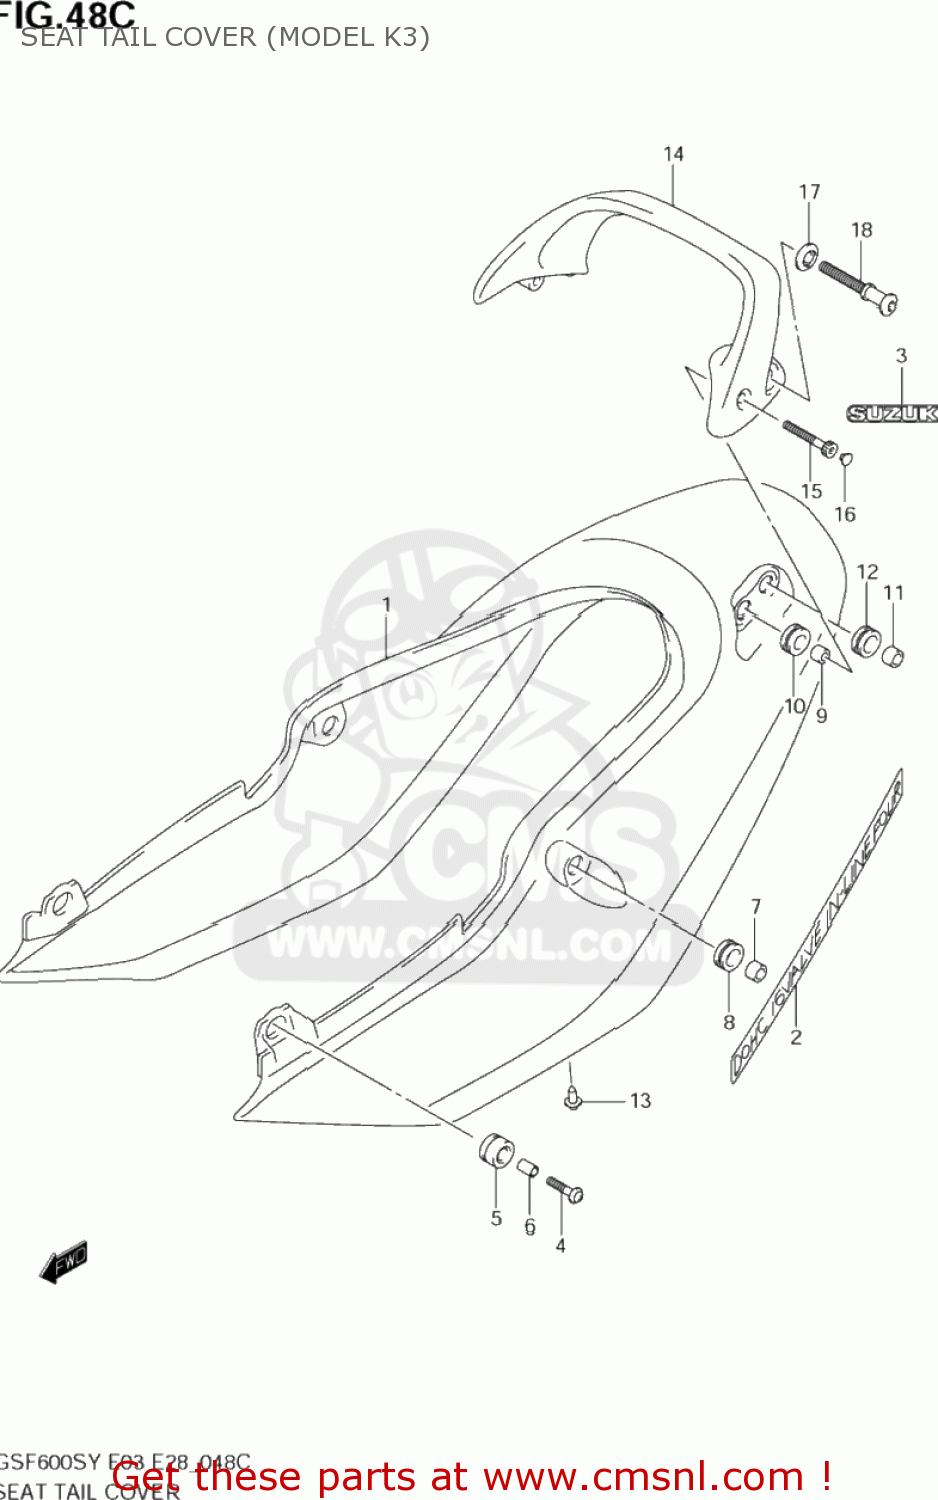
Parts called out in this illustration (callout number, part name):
1	COVER,SEAT TAIL
2	EMBLEM,SEAT TAIL COVER
3	EMBLEM,SUZUKI
4	SCREW(6X30)
5	CUSHION,SEAT TAIL COVER FR
6	SPACER(6.5X10X13)
7	SPACER,8.5X14X9
8	CUSHION
9	SPACER(6.5X12X9)
10	CUSHION
11	SPACER,8.5X14X9
12	CUSHION
13	CLIP(BLACK)
14	HANDLE,PILLION RIDER
16	CAP(OD:10)
17	WASHER,HOOK
18	HOOK,PILLION RIDER HANDLE
